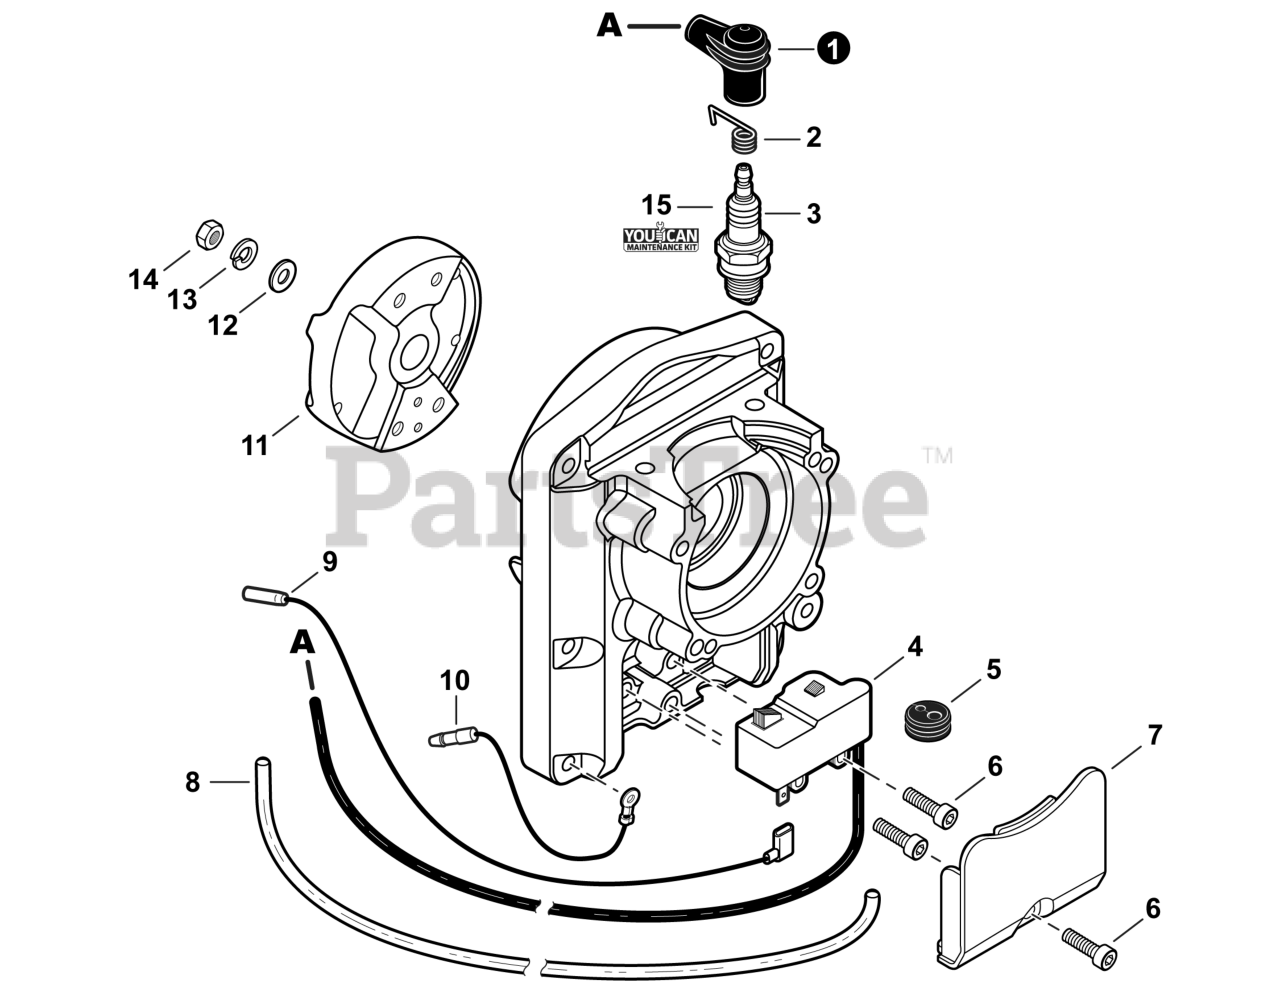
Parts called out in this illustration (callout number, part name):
1	CAP, SPARK PLUG
2	TERMINAL, SPARK PLUG
3	SPARK PLUG - BPM8Y
4	COIL, IGNITION
6	BOLT, TORX 5x16
7	COVER, DUST
9	LEAD - IGNITION
10	LEAD - GROUND
11	FLYWHEEL
12	WASHER M10
13	WASHER, SPRING 10
15	TUNE-UP KIT - YOUCANT
